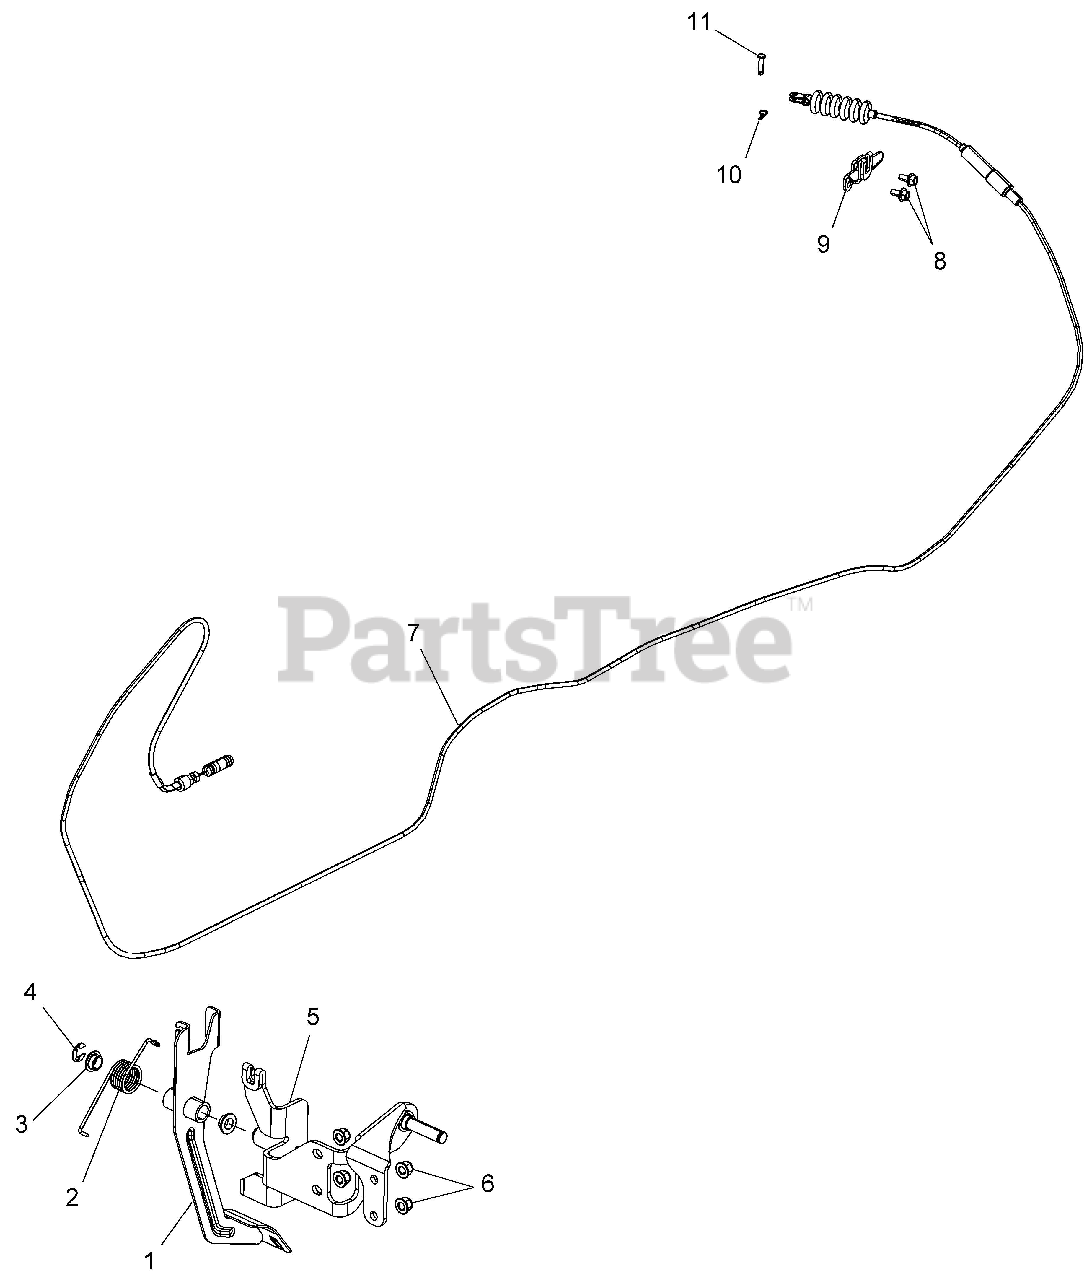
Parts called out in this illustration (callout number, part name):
1	WELD-THROTTLE PEDAL,BLK
2	SPRING-ACCELERATOR,HEAVY
3	BUSHING-PEDAL PIVOT
5	MOUNT, PEDAL, BLACK
6	NUT-M8X1.25,FLG,NYLOC-OLIVE D
7	CABLE, THROTTLE
9	BRKT-THROTTLE,ENGINE
10	HAIRPIN-COTTER 3/16-1/4
11	PIN,CLEVIS
